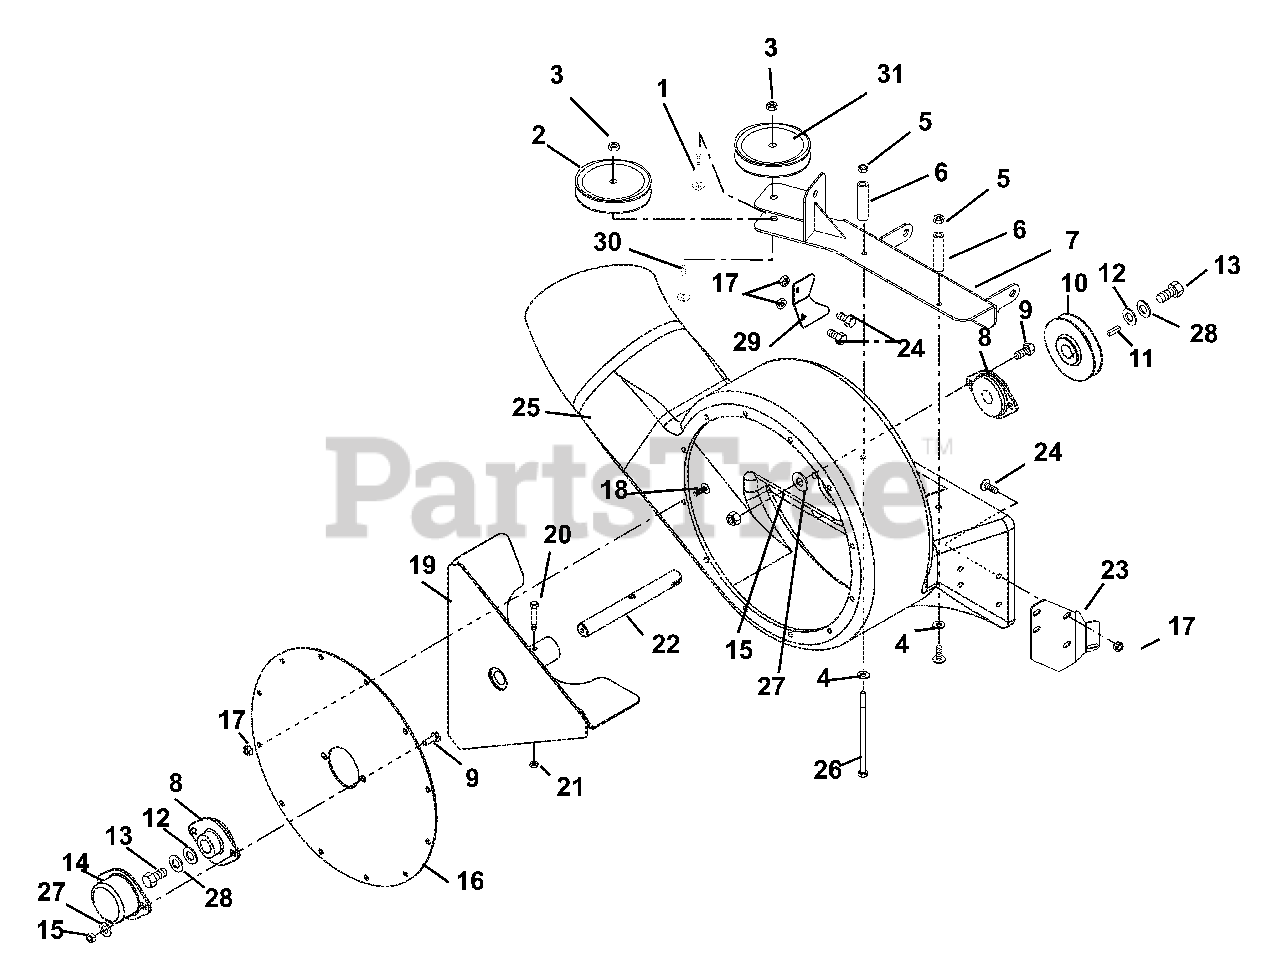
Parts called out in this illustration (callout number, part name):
1	@BLT-RDHDSQNK .38-16X1.50 G5YZ
2	IDLER-V 4.00 X .38 NWHAMSHR
3	@NUT-SPNLK-FLG .375-16 YWZC
4	@WSHR-FL-STL.281X.62X.065 YWZC
5	@NUT-LK-CTR .25-20 YWZC
7	WMT - BRACKET - MOUNTING
8	BEARING, 2 BOLT FLANGE -.75 ID
9	@BLT-HEX .31-18X1.00 GR5 YWZC
10	PULLEY, DRIVEN 3.50
11	KEY-SQ .187 X .50 X .187
12	WSHR-FL-STL .328X1.0X.094 YWZC
13	BLT-HEX .25-28X.75 GR5 YWZC
14	COVER-BEARING
15	@NUT-LK-NYL .312-18 YWZC
16	PLATE-BEARING MOUNTING
17	@NUT-SPNLK-FLG .25-20 YWZC
18	SCR-MCH .25-20X.50 TXTR PL
19	IMPELLER, GRASS PUMP
20	@BLT-HEX .25-20X1.50 GR5 YWZC
21	@NUT-LK-CTR .25-20 YWZC
22	SHAFT, GRASS PUMP - .75 OD
23	BRACKET-MOUNTING,DECK TO PUMP
24	SCR-MCH .25-20X.75 TXTR YWZC
25	HOUSING - GRASS PUMP
26	@BLT-HEX .25-20X4.50 GR5 YWZC
27	@WSHR-FL-STL.312X.734X.065 YWZ
28	@WSHR-LK .25X.062 REG YWZC
29	BRACKET-DECK STOP
30	@BLT-RDHDSQNK .38-16X1.25 G5YZ
31	IDLER FLANGED 3.50
